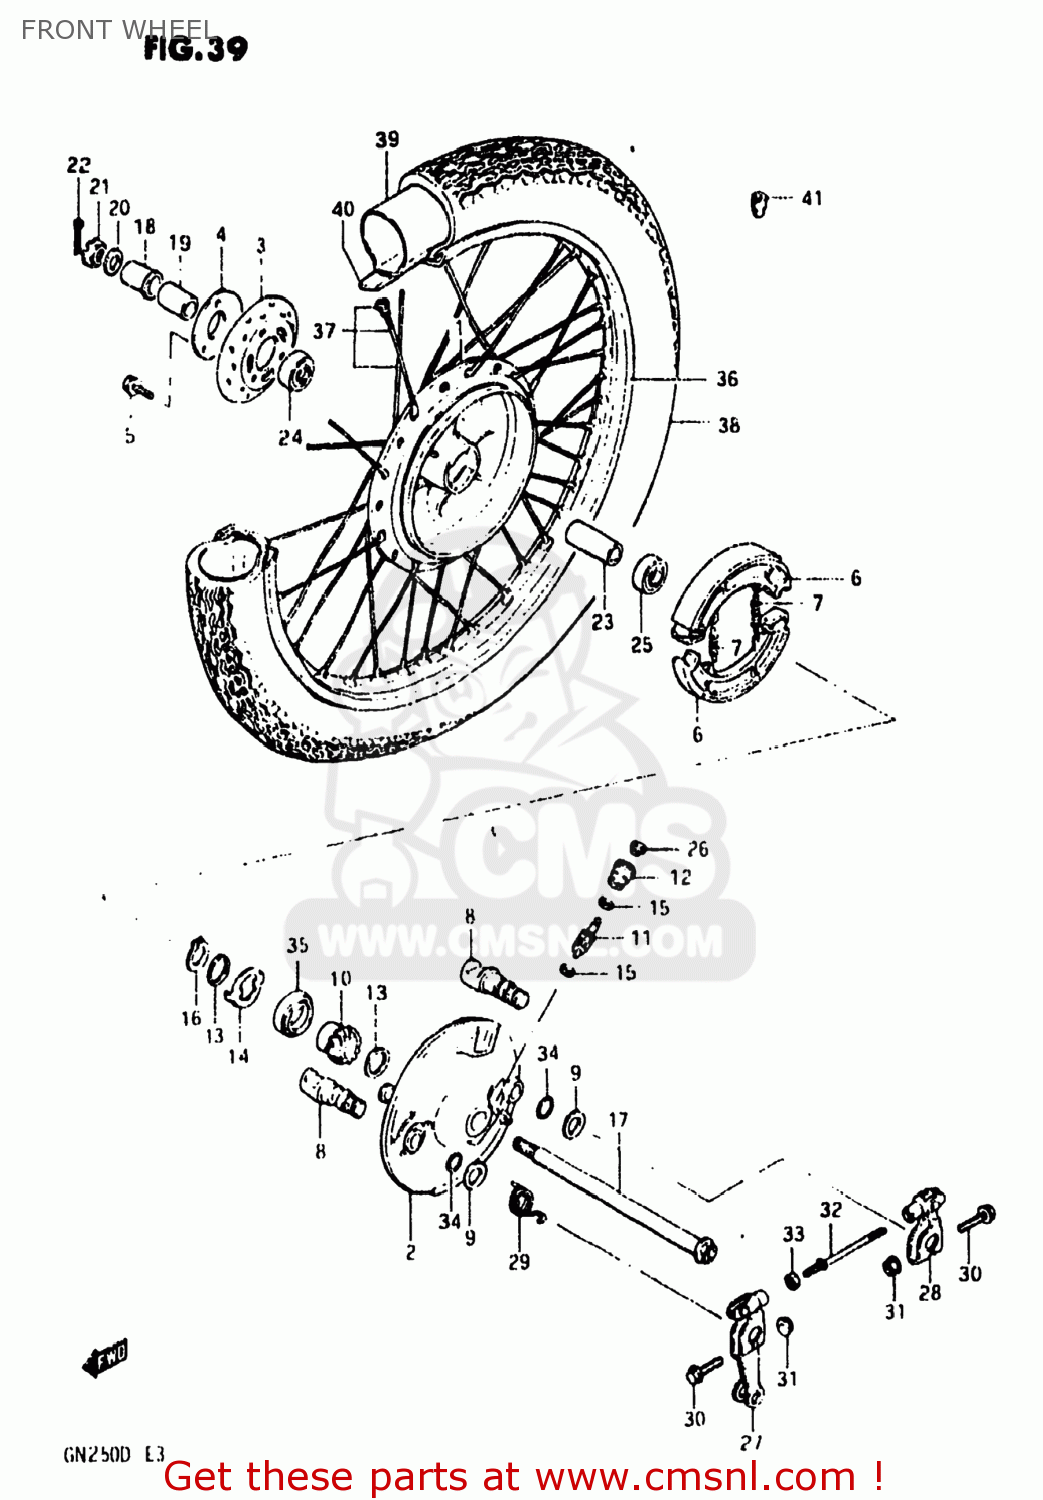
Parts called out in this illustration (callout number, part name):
1	HUB,FRONT
2	PANEL,FRONT HUB
3	FLANGE,FRONT HUB,RIGHT
4	PLATE,FRONT HUB BEARING
5	BOLT
6	SHOE,BRAKE
7	SPRING
8	CAM,FRONT BRAKE
9	WASHER (15X24X1.6)
10	GEAR,SPEEDOMETER
11	PINION,SPEEDOMETER
12	BUSHING,SPEEDOMETER PINION
13	WASHER(22.5X27X1)
14	DRIVER,SPEEDOMETER GEAR
15	WASHER (5.1X9X0.4)
16	CIRCLIP
17	AXLE,FRONT
18	SPACER,FRONT AXLE,LEFT
19	SPACER(12X20X34.5)
20	WASHER
21	NUT 12MM
22	COTTER PIN
23	SPACER (12.6X19X52)
24	BEARING, RH
25	BEARING
26	SEAL,OIL(6X10X3)
27	LEVER ASSEMBLY,FRONT BRAKE CABLE
28	LEVER, BRAKE CAM NO.2
29	SPRING
30	BOLT
31	NUT
32	ROD,BRAKE CAM LEVER CONNECTION
33	NUT 6MM
34	O-RING,BOSS
35	SEAL,OIL(26X38X4)
36	RIM,FRONT WHEEL (1.60X1
37	SPOKE SET,FRONT
38	TIRE,FRONT
39	TUBE,INNER
40	PROTECTOR,INNER TUBE
41	BALANCER,WHEEL (B)
